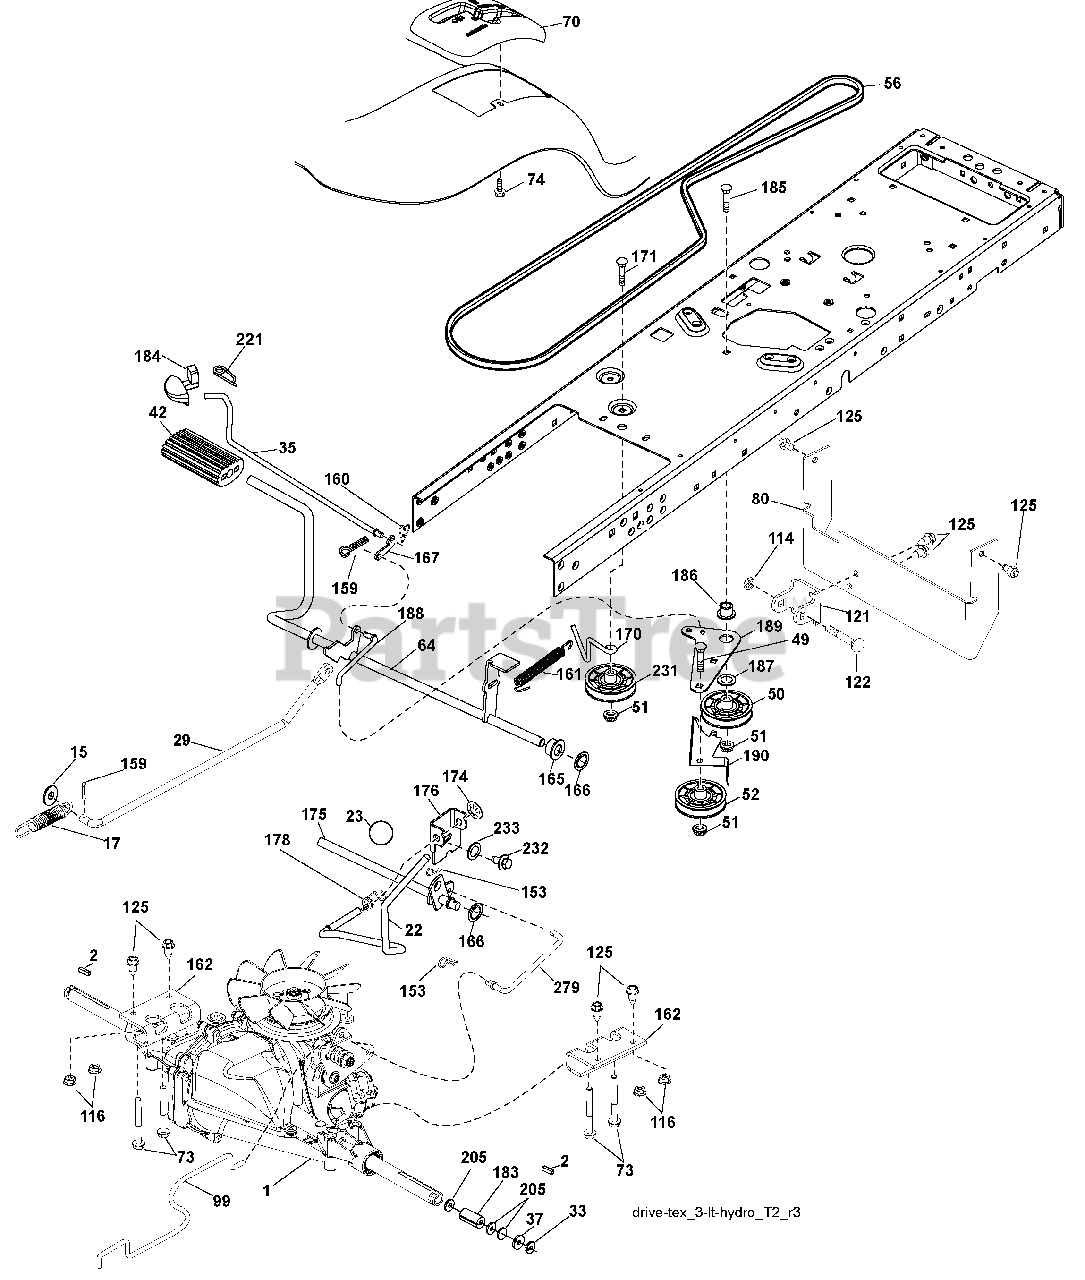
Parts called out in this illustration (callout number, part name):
1	Transaxle, Hydro Gear T2 (See Transaxle Breakdown)
2	Key Square
15	Washer 13/32 x 13/16 x 16 Ga.
17	Spring, Brake
22	Rod Shift
23	Knob
29	Rod, Brake
33	Ring E
35	Rod, Brake, Park
37	Washer 25/32 x 1-1/4 x 16 Ga.
42	Cover, Foot Pedal
49	Bolt
50	Pulley Idler Flat
51	Lock Nut 3/8-16
52	Idler V-Groove 910" Offset
56	V-Belt, Drive
64	Shaft Asm. Pedal Brake Control
70	Console
73	Bolt Hex 5/16-18 Gr. 5
74	Screw 1/4 x 1/2
80	Strap Torque
99	Rod Spring Bypass
114	Nut Lock 5/16-18 UNC
116	Nut Lock Hex Flange 5/16-18
121	Bracket Strap Torque
122	Bolt 5/16-18 x 2.50
125	Screw 5/16-18 x 3/4
153	Retainer Spring 1"
159	Pin Cotter 1/8 x 3/4
160	Retainer Clip
161	Spring, Return, Clutch
162	Adapter, Transaxle T2
165	Bushing
166	Nut Push .625
167	Latch Brake Parking
170	Keeper Belt Centerspan
171	Bolt
174	Nut Push
175	Shaft Asm Shift
176	Arm Clevis Rod Shift
178	Spring Shift
183	Spacer Axle
184	Handle Parking Brake
185	Bolt
186	Spacer Retainer
187	Washer
188	Link Clutch Ground Drive
189	Bellcrank Ground Drive
190	Keeper Bellcrank Ground Drive
205	Washer 25/32 x 1-5/8 x 16 Ga.
231	Idler V-Groove 1.688" Offset
232	Bolt 7/16-14 x 1 Gr 5
233	Washer Serrated
279	Link Shift
